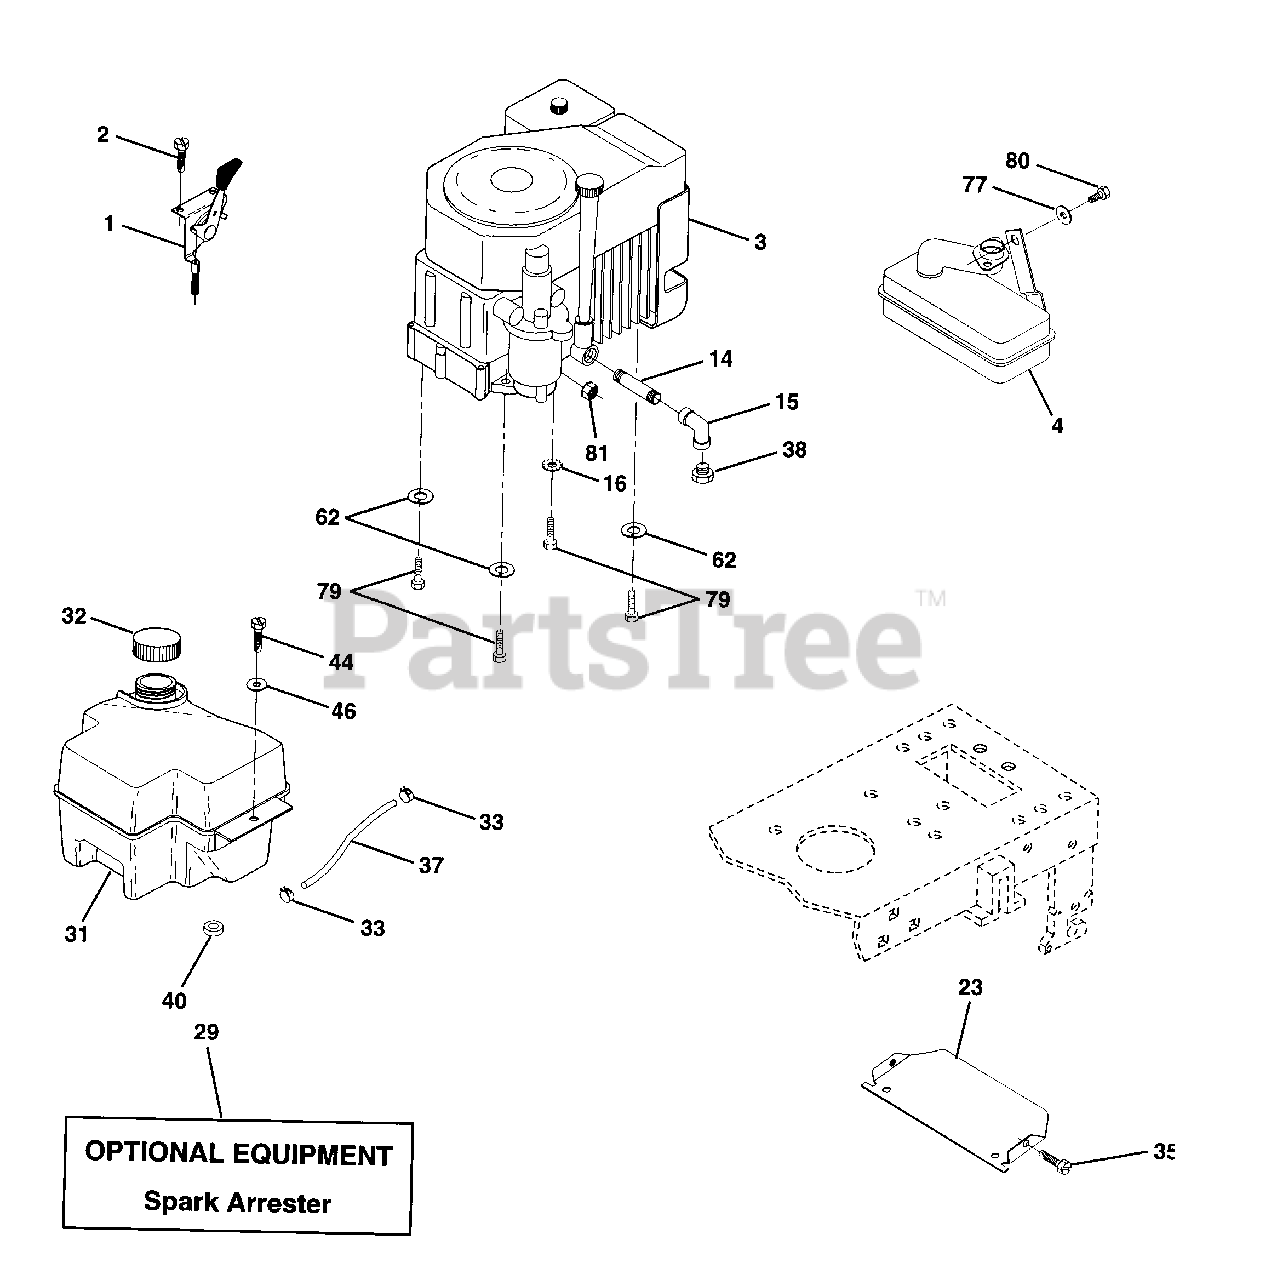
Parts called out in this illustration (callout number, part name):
1	Control THTICH 27 LH FLAG DOM
2	Screw Hex Thd Cut 1/4-20 x 5/8 T
3	Engine Kohler, Model No. CV15S 15 HP
4	Muffler LT Kohler 12.5/15HD
14	Nipple Pipe 3/8 Npt x 3-1/2
15	Elbow Std 90 Degree 3/8-18 Npt
16	Washer Lock Ext Tooth 5/16
23	Shield Heat
29	Kit Spark Arrestor (Flat Scrn)
31	Tank Fuel Front 2 00
32	Cap Asm Fuel W/sym Vented
33	Clamp Hose Black
35	Screw
37	Line Fuel 20"
38	Plug Oil Drain
40	Bushing Snap Nyl Blk Fuel Line
44	Screw Hexwsh Thdrol 1/4-20 x 3/4
46	Washer 9/32 x 7/8 x 16 Ga
62	Washer Lock Hvy Hlcl Spr 5/16
77	Washer 5/16 x 3/4 x 16 Ga.
79	Bolt Hex
80	Bolt Hex Hd 5/16-18 UNC x 1/2
81	Nut Flange 1/4-20 Starter Nut
